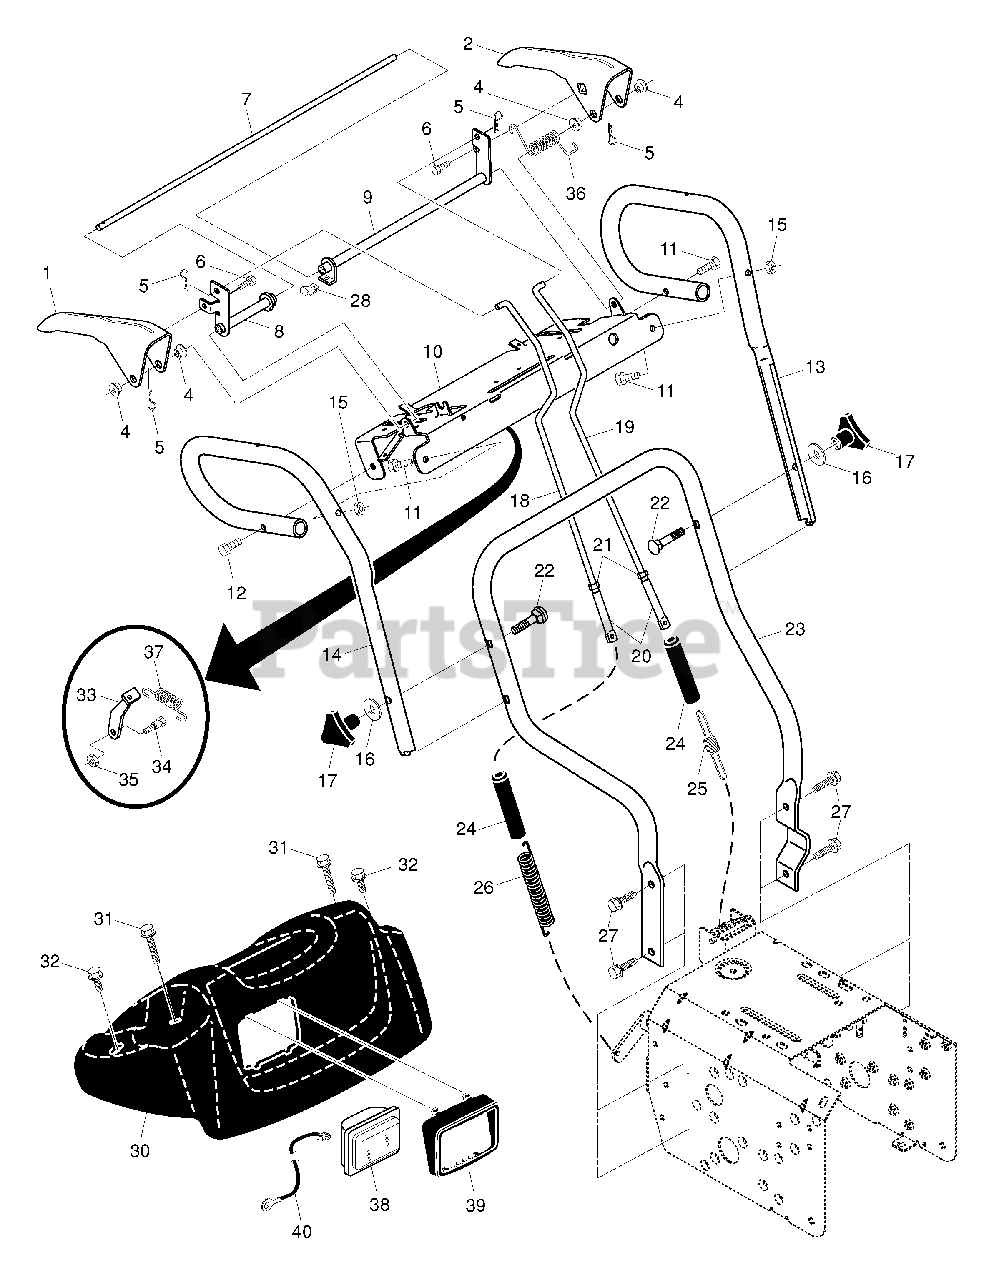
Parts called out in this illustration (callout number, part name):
1	Lever, Auger Control, RH
2	Lever, Traction Drive Control, LH
4	Bushing, Flange
5	Retainer, Hairpin
6	Screw, Hex Head 1/4-20 x 3/4
7	Rod, Interlock
8	Tube Assembly, Interlock, RH
9	Tube Assembly, Interlock, LH
10	Panel, Control
11	Screw, Hex Head 5/16-18 x 1-1/2
12	Screw, Hex Head 5/16-18 x 1-3/4
13	Handle Tube, LH
14	Handle Tube, RH
15	Nut, Lock 5/16-18
16	Washer, Flat 3/8
17	Knob, Handle
18	Rod, Auger Control
19	Rod, Traction Control
20	End, Control Rod
21	Nut, Hex, Jam 5/16-18
22	Bolt, Carriage 3/8-16 x 2-1/4
23	Handle Tube, Lower
24	Sleeve, Spring
25	Spring, Traction Drive
26	Spring, Auger Control
27	Screw, Hex Head 3/8-16 x 1
28	Clip, Panel
30	Console, Panel
31	Screw, Hex Head, Tapping #10-24 x 1-1/4
32	Screw, Hex Head, Tapping #10-24 x 1/2
33	Latch, Interlock
34	Bolt, Shoulder
35	Nut, Lock 1/4-20
36	Spring, Torsion, Lever
37	Spring, Interlock
38	Headlight, Flood
38	Bulb, Flood
39	Bezel, Headlight
40	Harness, Headlight (Flood)
